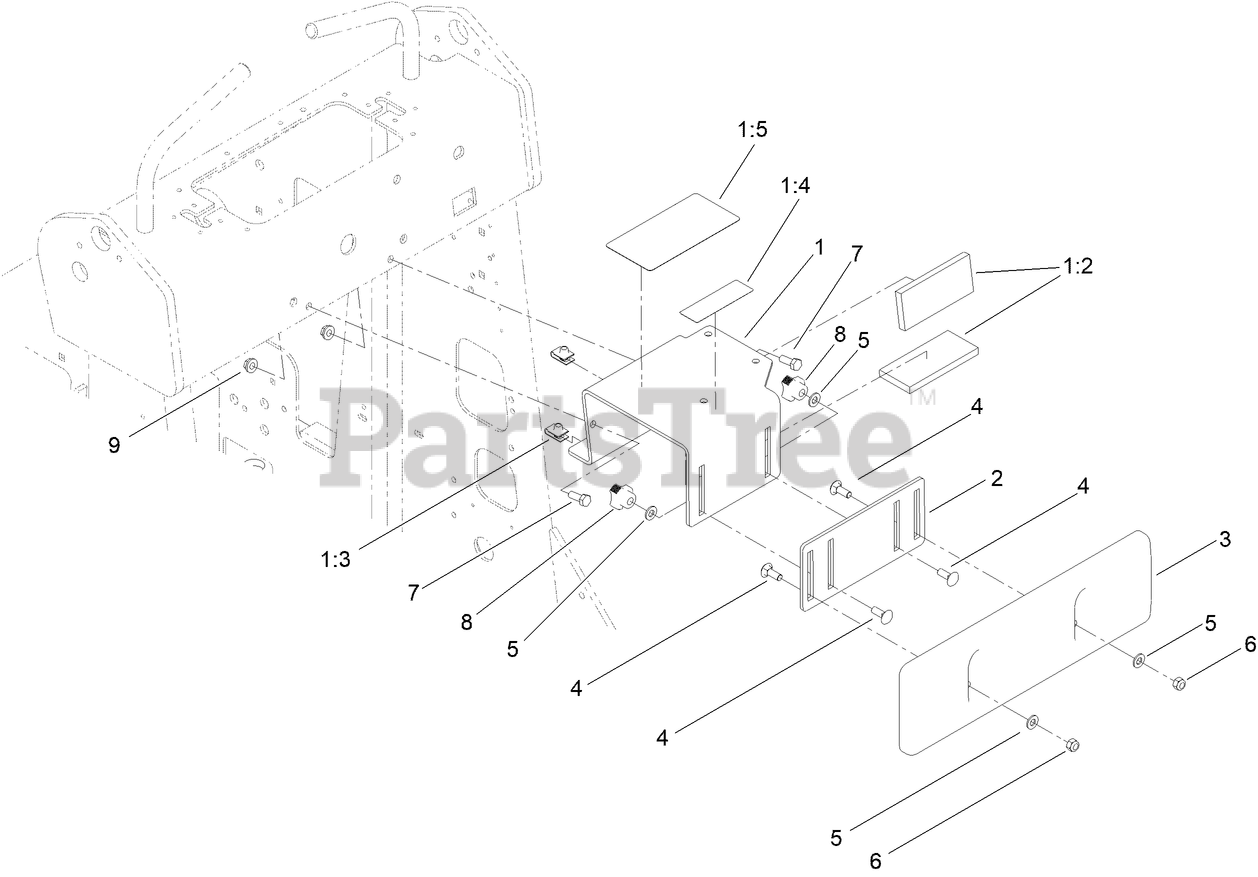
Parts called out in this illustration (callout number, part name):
1	THIGH SUPPORT BRACKET ASM
1:2	PAD-FOAM
1:3	NUT-CLIP, U
1:4	DECAL-MANUAL
1:5	DECAL-SERVICE
2	PLATE-ADJUSTING
3	SUPPORT-THIGH
4	SCREW-CARR
5	WASHER-FLAT
6	NUT-LOCK, NI
7	SCREW-HH
8	KNOB-ADJUSTMENT
9	NUT-HF
